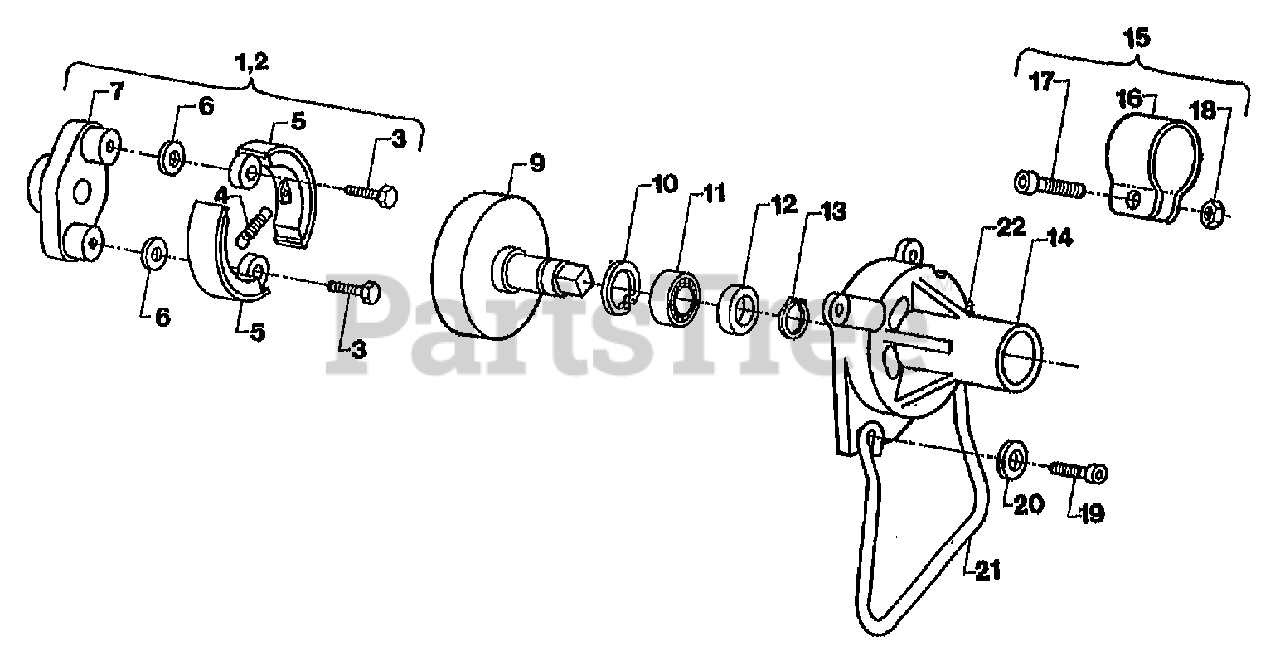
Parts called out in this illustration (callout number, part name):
1	ASSM-CLUTCH (COMPLETE)(INCL. 3-7)
2	ASSM-CLUTCH (COMPLETE)(INCL. 3-6)
3	SCREW, HEX. HD., CLUTCH
5	SHOE, CLUTCH
6	WASHER, FLAT 1/4 ID CLUTCH
7	ROTOR THREADED-CLUTCH
9	ASSM-DRUM & ARBOR
10	RING-RETAINING
13	RING-RETAINING
14	HSG-CLUTCH W/BEARING (INCL. 11-13)
15	KIT (INCL. 16-18)
16	CLAMP
17	SCREW, 1/4"-20X3/4" SOCKET HD CAP
18	NUT, 1/4"-20 CLAMP
19	SCR-HXSKT 1/4-20X.75
20	WASHER-MOTOR LEG
21	LEG-MOTOR
22	GREASE FIT.THD.
